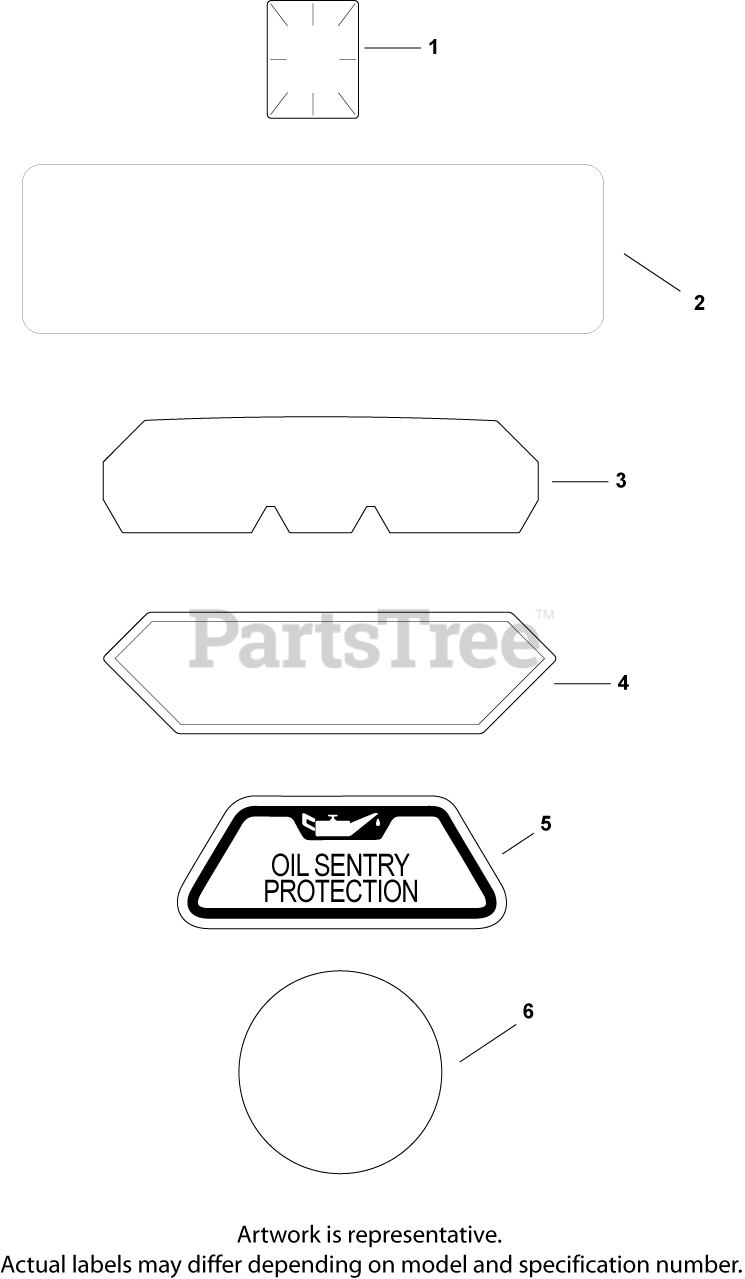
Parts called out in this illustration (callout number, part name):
1	DECAL, CLEAR LAMINATE USE 25 113 70-S
2	DECAL, 23 HP - DISCONTINUED
3	DECAL, HEAT REFLECTIVE
4	DECAL, MTD CUB CADET LOGO
5	DECAL, OIL SENTRY - (#DSC)
6	LABEL, (ROUND KOHLER GOLD)-USE 24 113 18
